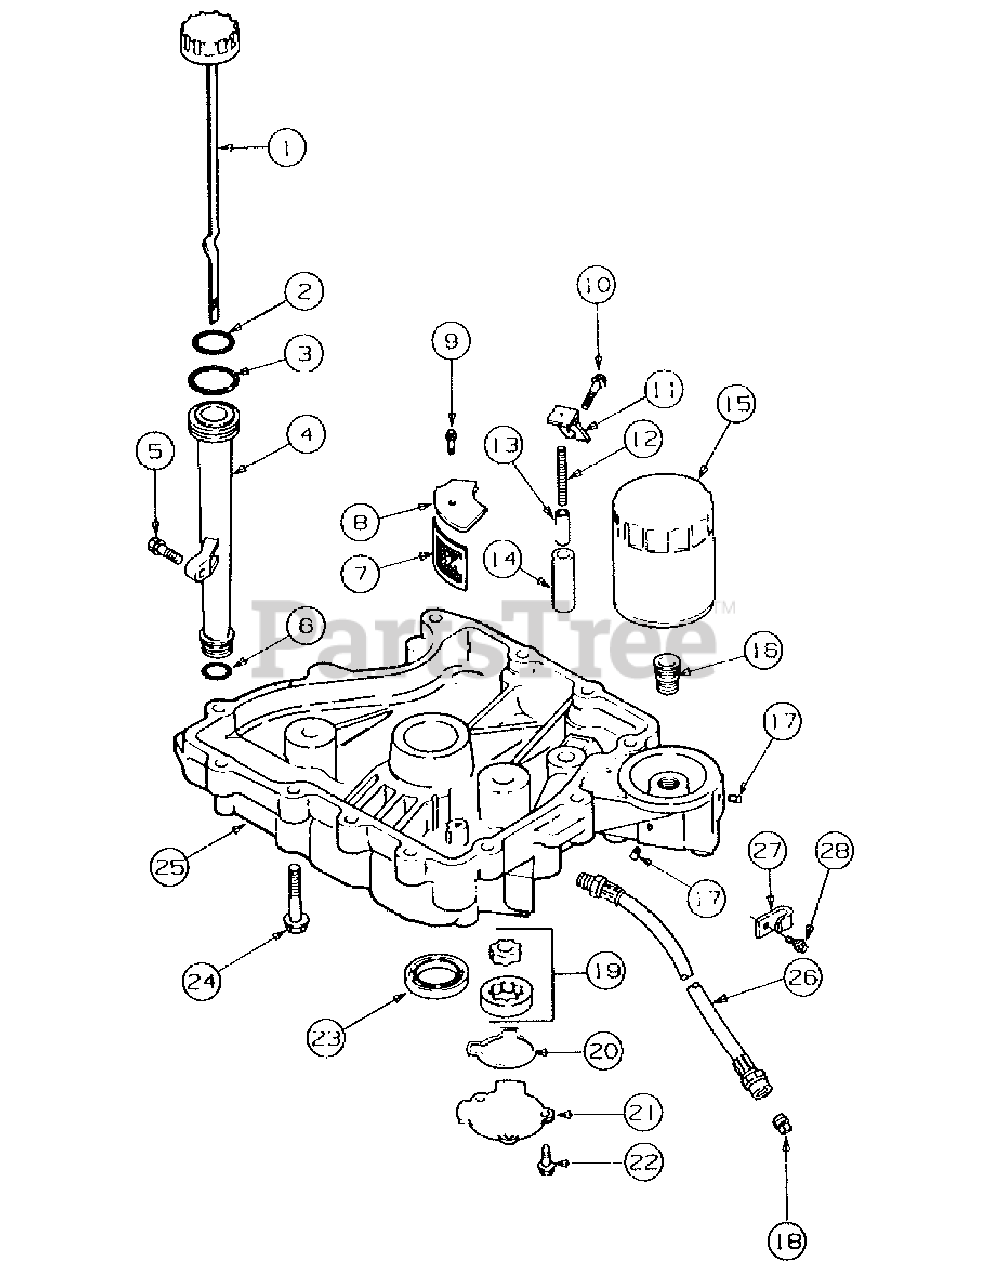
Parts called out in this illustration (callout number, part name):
1	Dipstick Ass'y
2	O-Ring, Dipstick
3	O-Ring, Upper Oil Fill Tube
4	Tube, Oil Fill
5	Screw, Oil Fill Tube, M5 x 0.8 x 20
6	O-Ring, Lower Oil Fill Tube
7	Screen ,Oil Pickup
8	Cover, Oil Pickup Screen
9	Screw, Screen Cover
10	Screw, Oil Pump Relief Valve Bracket
11	Bracket, Oil Pump Relief Valve
12	Spring, Oil Pump Relief Valve
13	Piston, Oil Pump Relief Valve
14	Body, Oil Pump Relief Valve
15	Filter, Oil
16	Adapter, Oil Filter
17	Plug, Sq Hd Solid, 1/8 NPTF
18	Plug, Sq Hd Solid, 3/8 NPTF
19	Pump, Oil Ass'y
20	O-Ring, Oil Pump Cover
21	Cover, Oil Pump
22	Screw, Oil Pump Cover, M5 x 0.8 x 16
23	Seal, Oil (PTO end)
24	Screw, Oil Pan, M8 x 1.25 x 45
26	Hose, Oil Drain
27	Clip, Drain Hose
28	Screw, Hex Wash Hd Tapp, 5/16-18 x .50 Lg
